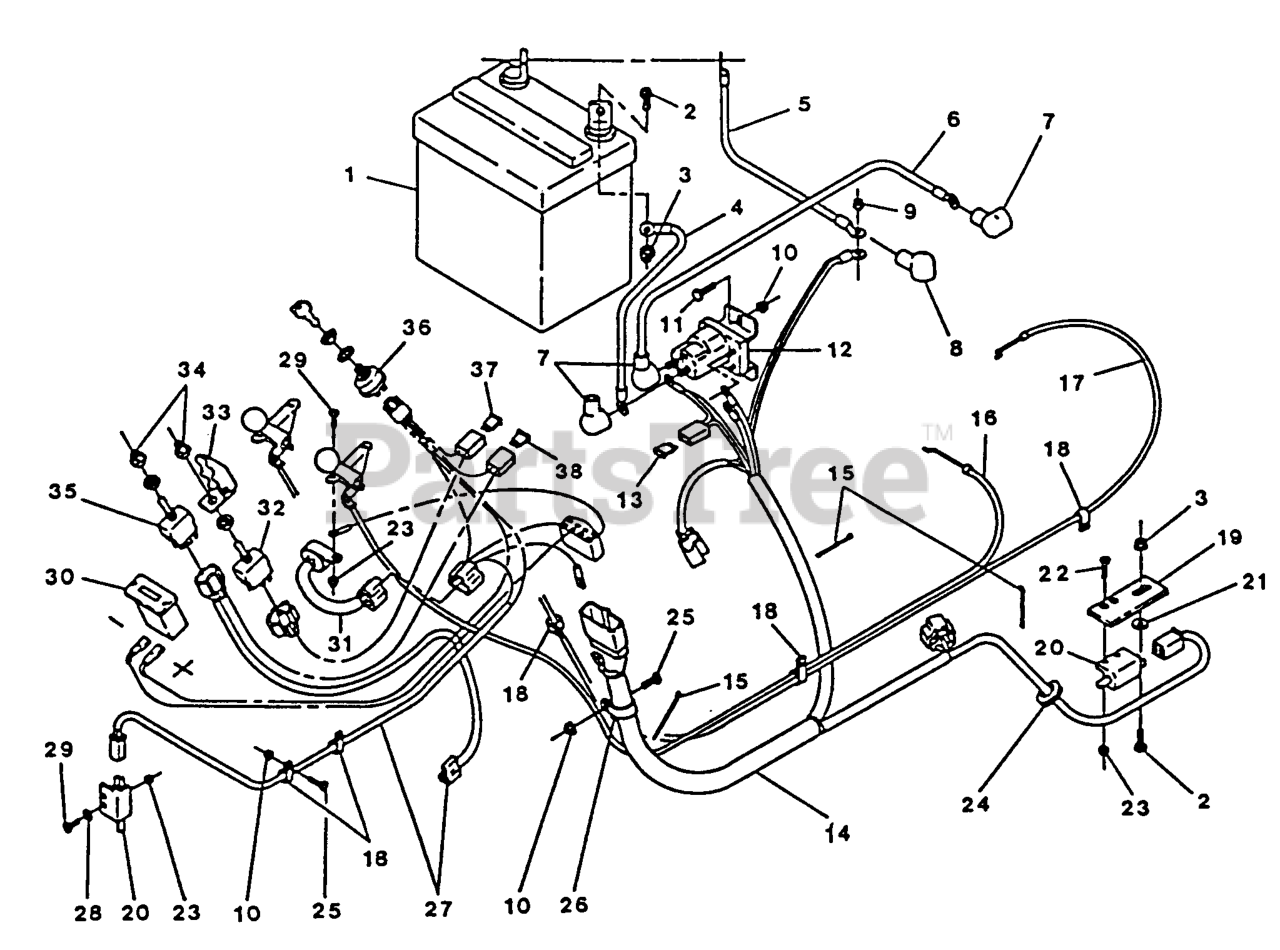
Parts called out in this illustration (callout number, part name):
4	WIRE,BATTERY POSITIVE
5	WIRE-GROUND
7	INSULATOR-SOLENOID
13	FUSE-BLADE TYPE, 20 AMP
15	TIE-CABLE
19	BRACKET-SAFETY SWITCH
20	SWITCH-OPEN, NORMALLY
24	GROMMET
26	CLIP-LOOM
30	METER-HOUR
34	BOOT-SWITCH, TOGGLE
35	SWITCH-TOGGLE, DPDT
38	FUSE-BLADE TYPE, 30 AMP
